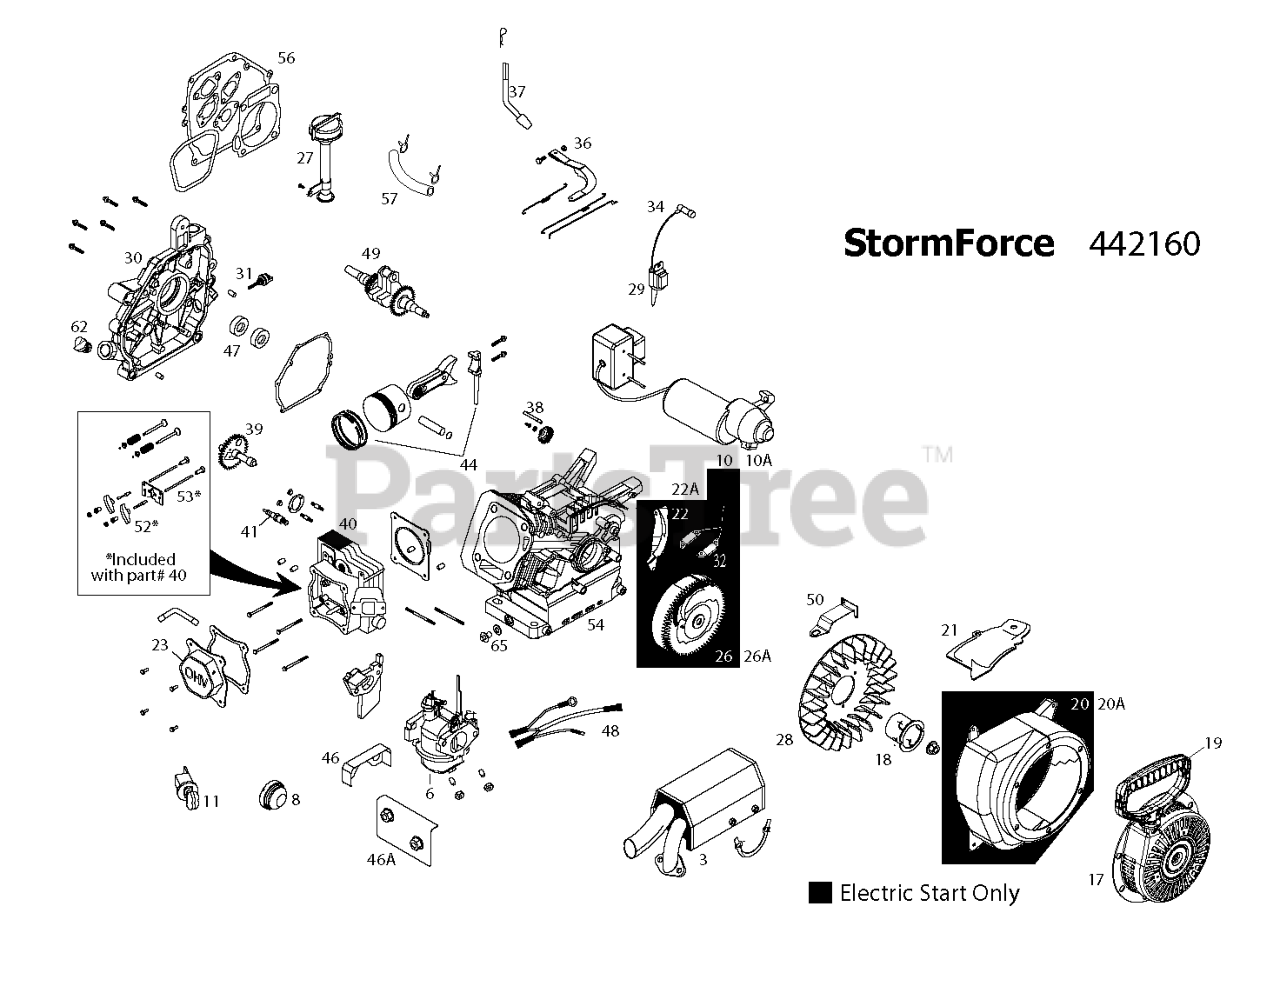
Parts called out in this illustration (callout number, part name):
3	MUFFLER.ASM.LCT.208CC.SNGL.STG
6	CARB.ASM.SS/SNO.LCT(SKSNO313)
8	BULB.FUEL.PRMR.W/HOSE(SKSNO306
10	STARTER.ASM.ELEC.(SKSNO411)
10A	STARTER STARTER.EURO
11	SWITH.KEY.ASSEM.SNOW.SINGLE.ST
17	RECOIL.STRT.ROUND(BLK) SNOW
18	STRTER.CUP(NON-SLOT)SKSN0601.2
19	HANDLE.RECOIL.DELUXE.LCT
20	BLOW.HSG.ASSY.ELEC(SKSN-0602)
20A	BLOW.HSG.ASSY.ELEC(SKSN-0612)
21	SHILED.FLYWEEL.SYS(SKSN-0604)
22	SHLD.ELEC.START.FLY(SKSN-0605)
22A	SHIELD.FLYWEEL.MAN(SKSN-0607)
23	VALVE COVER ASSEMBLY
26	FLYWHL.ASSY.ELECT.(SKSN0405)
26A	RP KIT.FLYWHEEL.SERVICE
27	HIGH OIL-FILL TUBE ASSY
28	FLYWHEEL FAN 420586
29	COIL.ING.CDI.HI TEMP.SKSNO416.
30	CRANKCASE COVER ASSY
31	DIPSTICK SMALL
32	CHARGING.COILS.18-WATT
34	SPARK.PLUG.BOOT.SNW,SKSN4691.1
36	RP_IT.GOVERNOR.ARM(SUMMER ENG)
37	KIT.GOVERNOR.CRANK(SK208-3100)
38	GOVENOR.GEARS ASM(SK2082900)
39	KIT.CAMSHAFT.208CC.LCT
40	CYLINDR.HEAD.SRV.KIT W/GASKET
41	SPARK.PLUG(2083810)
44	KIT.PISTON.SRV(SK208-1400)
46	SHIELD.VAPOR.SNOW
46A	SHIELD.INTAKE.(LCT.SKSN0140.1)
47	SEAL KIT (2 PCS)
48	HARNESS.WIRE.SINGLE.STAGE.LCT
49	CRANKSHAFT-KEYED(SK2081800.1)
50	SPEED.CTRL.BRKT.(SKSN0150)
52	ROCKER ARM KIT
53	KIT.PUSH.ROD.SRV(SK208-1001)
54	CYLINDER.ASM.SKSN0001.2
56	GASKET.KIT.208CC(SK2084300.1)
57	KIT.FUEL.HOSE.208CC.SING/STAGE
62	NON REMOVABLE PLUG
65	KIT.OIL.DRAIN.PLUG(SK2089911
